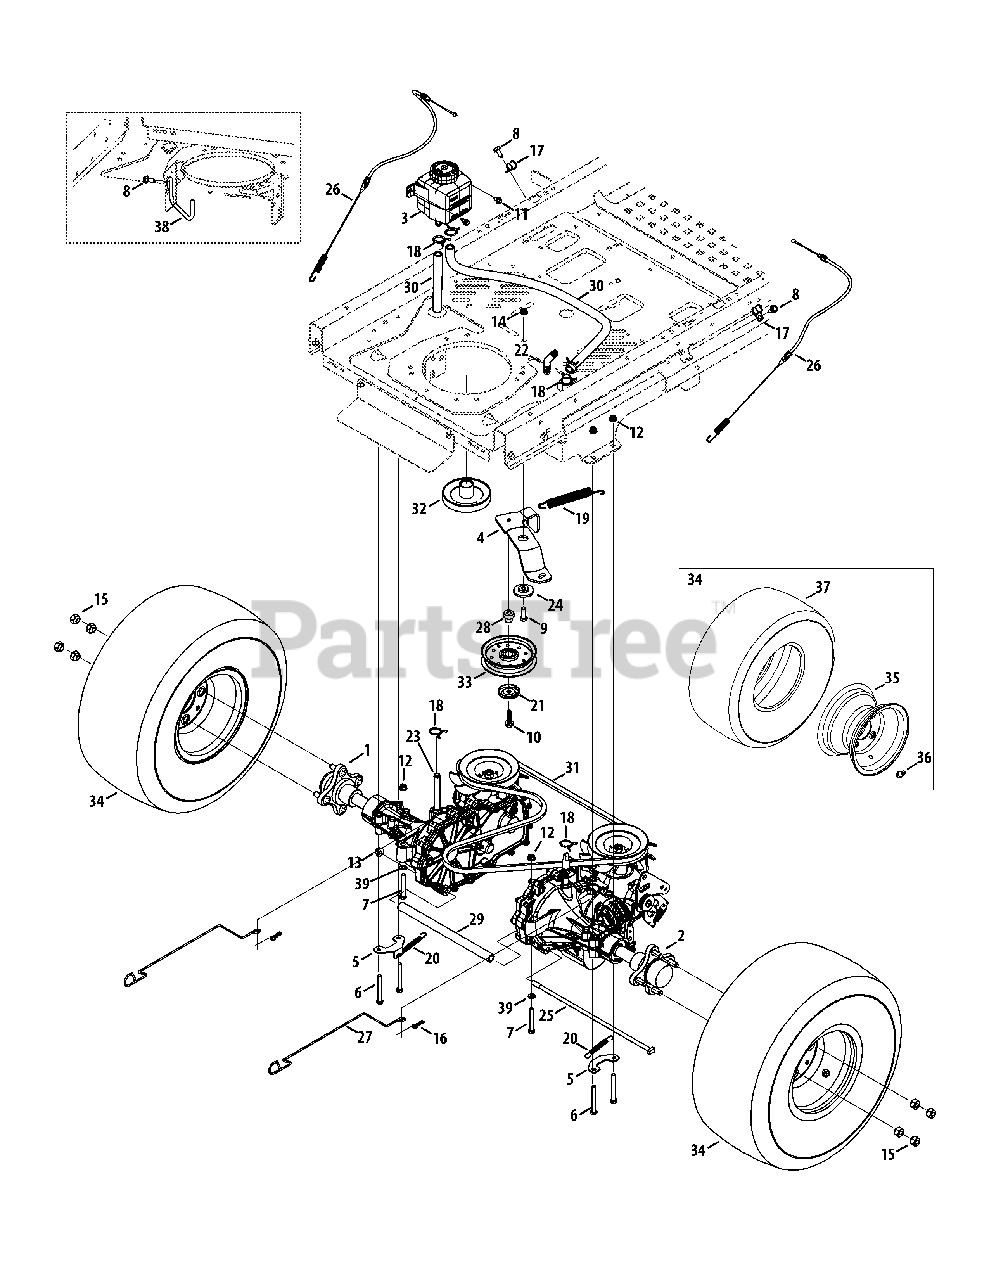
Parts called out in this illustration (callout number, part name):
1	Transmission Assembly, LH
2	Transmission Assembly, RH
3	Expansion Tank Assembly
4	Idler Bracket
5	Brake Mounting Bracket
6	Hex Screw, 5/16-18 x 2.75
7	Hex Cap Screw, 5/16-18 x 2.25
8	Hex Washer Screw, 5/16-18 x .750
9	Hex Screw, 3/8-16 x 1.00
10	Hex Washer Screw, 3/8-16 x 1.250
11	Hex Washer Screw, 1/4-20 x .625
12	Flange Lock Nut, 5/16-18
13	Flange Lock Nut, 3/8-16
14	Jam Lock Nut, 3/8-16
15	Lug Nut, 7/16-14
16	Bow-Tie Cotter Pin
17	Clamp 9/16 Dia.
18	Hose Clamp, .75 Dia. x .312
19	Extension Spring, .75 Dia. x 6.02
20	Extension Spring, .38 OD x 3.25 LG
21	Pulley Cap
22	Elbow, 90
23	Fitting, 9/16, Barb
24	Shoulder Spacer, .884 x .190
25	Rod, .337 Dia. x 14.75 LG
26	Park Brake Cable
27	Bypass Rod
28	Shoulder Spacer
29	Spacer, .75 OD x 11.31 LG
30	Fuel Hose, 1/2 ID
31	Belt, A-Type x 67.0
32	Engine Pulley
33	Idler Pulley, 4.25 Dia.
34	Complete Wheel, 20 x 10-8
36	Valve Tubeless
37	Tire Only
38	Engine Keeper Rod
39	Flat Washer .330 ID x .630 OD
